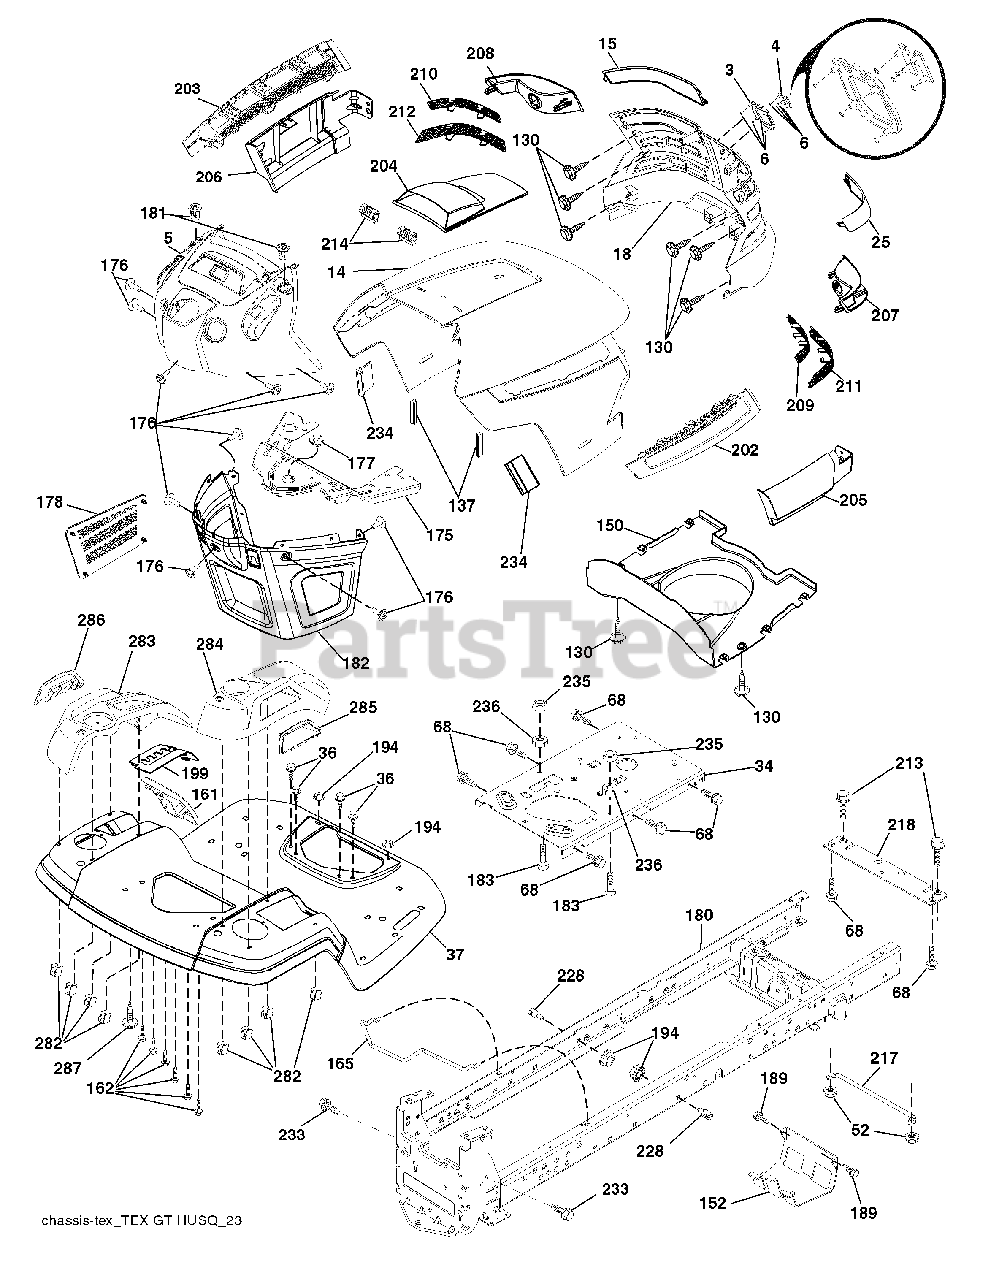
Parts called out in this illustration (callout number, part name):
3	Trim, Husq.
4	Logo
14	Hood
18	Grille/Lens Asm.
34	Plate Engine
36	Screw 5/16-18 x 3/4
37	Fender
52	Nut Lock 5/16-18
68	Screw Thdrol 5/16-18 x 1/2
130	Screw 10 x .750 BOS Thread
137	Bumper Dash
152	Shield Browning
161	Fuel Window
162	Screw Hex Wsh 1/4 x 1/2 unc
165	Support Tank Rear
175	Crossmember
176	Screw 10-24 x 5/8
177	Bushing Steering
178	Cargo Net Asm.
180	Chassis
181	Bushing Mtg. Fender Crgo
182	Dash Lower
183	Bolt Fin Hex 5/16-18 unc x 1-1/4
189	Screw 5/16-18 x 3/4
194	Nut Lock Hex Flange 5/16-18
199	Plate Deck Lift
202	Vent Side Hood RH
203	Vent Side Hood LH
204	Vent Top Hood
205	Skirt Hood Side RH
206	Skirt Hood Side LH
209	Insert Hex Top RH
210	Insert Hex Top LH
211	Insert Hex Bottom RH
212	Insert Hex Bottom LH
213	Bolt 5/16-18 x 3/4
214	Clip Retainer Tinner
218	X-Piece Hood Stop
228	Stud Fastner
233	Bolt, Shoulder
234	Bumper Hood
235	Spacer Fender
236	Nut Lock 5/16-18 UNC
282	Clip Retainer Console
283	Console Deck Lift
284	Console Shift
285	Console Insert RH
286	Console Insert LH
287	Screw 1/4-20 X 3/8
